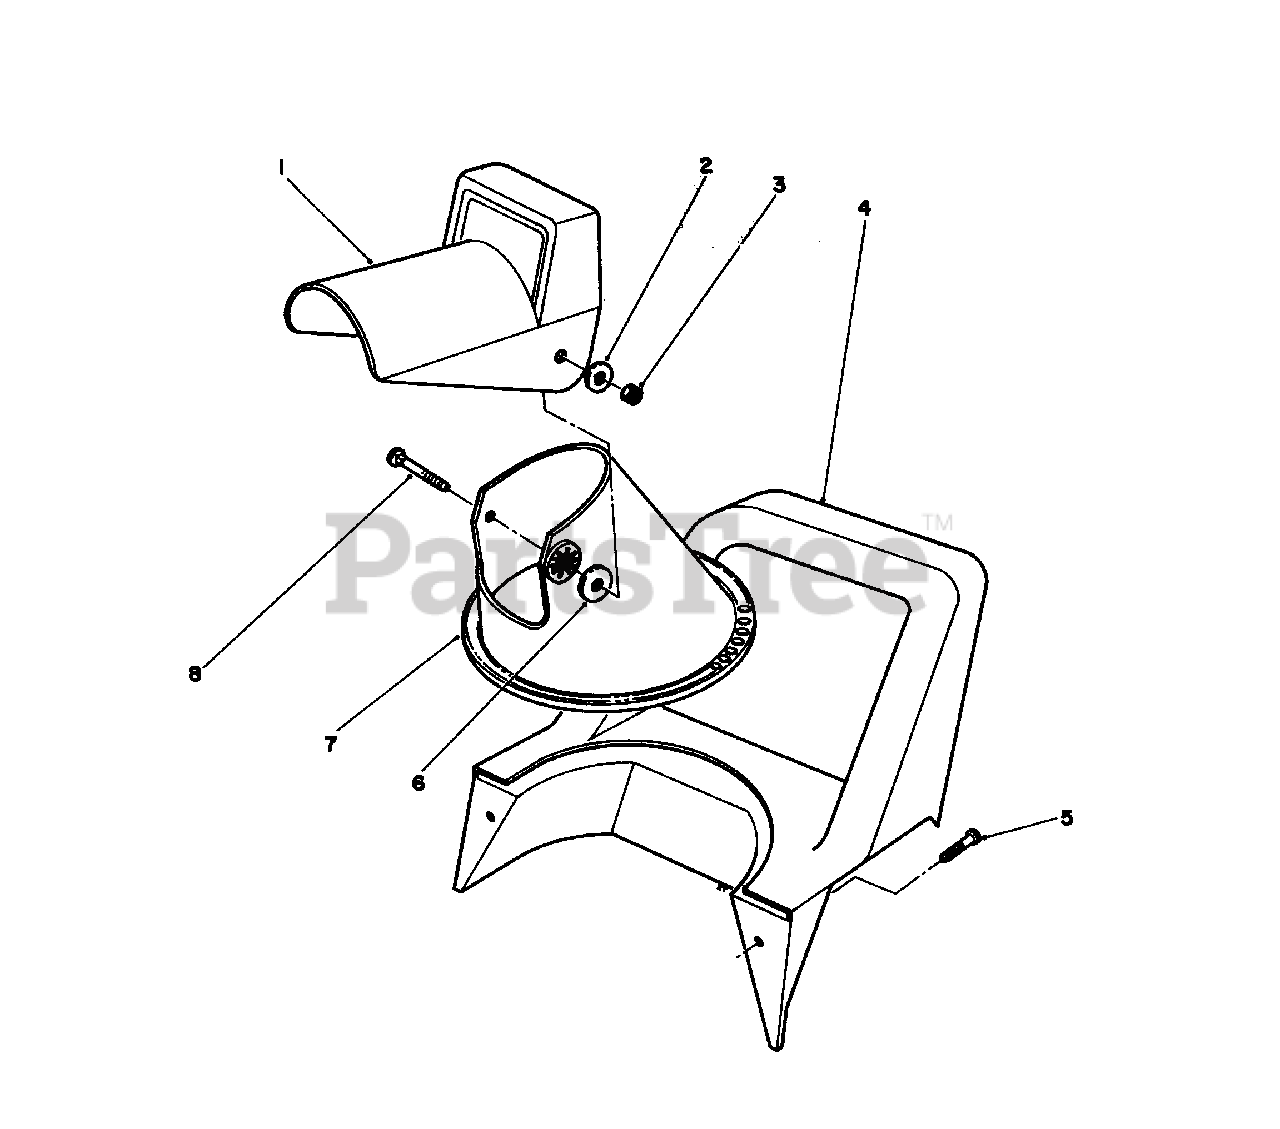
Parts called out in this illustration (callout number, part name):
1	Chute-Deflector
2	Washer-Flat
3	Nut-Lock
4	Handle-Middle
5	Screw-Pan Hd. Form.
6	Washer-Rubber
7	Chute-Lower
8	Bolt-Carriage
